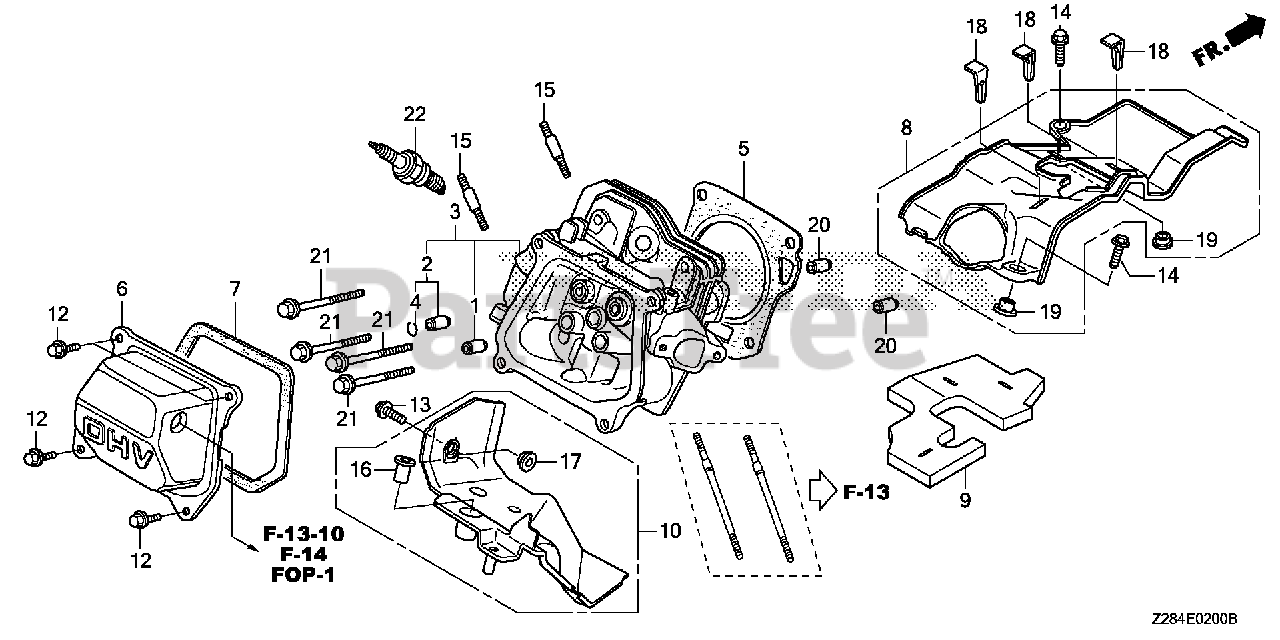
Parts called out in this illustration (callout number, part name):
1	GUIDE, VALVE (OVER SIZE) Use from Engine SN 6324986.
2	GUIDE, EX. VALVE (OS)
3	CYLINDER HEAD
4	CLIP, VALVE GUIDE Use from Engine SN 1231803.
5	GASKET, CYLINDER HEAD
6	COVER, HEAD
7	GASKET, CYLINDER HEAD COVER
8	SHROUD (UPPER)
9	INSULATOR, SHROUD (UPPER)
10	SHROUD (LOWER)
12	BOLT, FLANGE (6X12) (CT200)
13	BOLT, FLANGE (6X14)
14	BOLT, FLANGE (6X20) (CT200)
15	BOLT, STUD (8X32)
16	COLLAR A, SHROUD (LOWER)
17	COLLAR B, SHROUD (LOWER)
18	CLIP, INSULATOR BIND (A)
19	COLLAR, RECOIL STARTER
20	PIN A, DOWEL (10X16)
21	BOLT, FLANGE (8X60)
22	SPARK PLUG (BPR5ES) (NGK)
22	SPARK PLUG (W16EPR-U) (DENSO)
22	SPARK PLUG (BPR6ES) (NGK)
22	SPARK PLUG (W20EPR-U) (DENSO)
